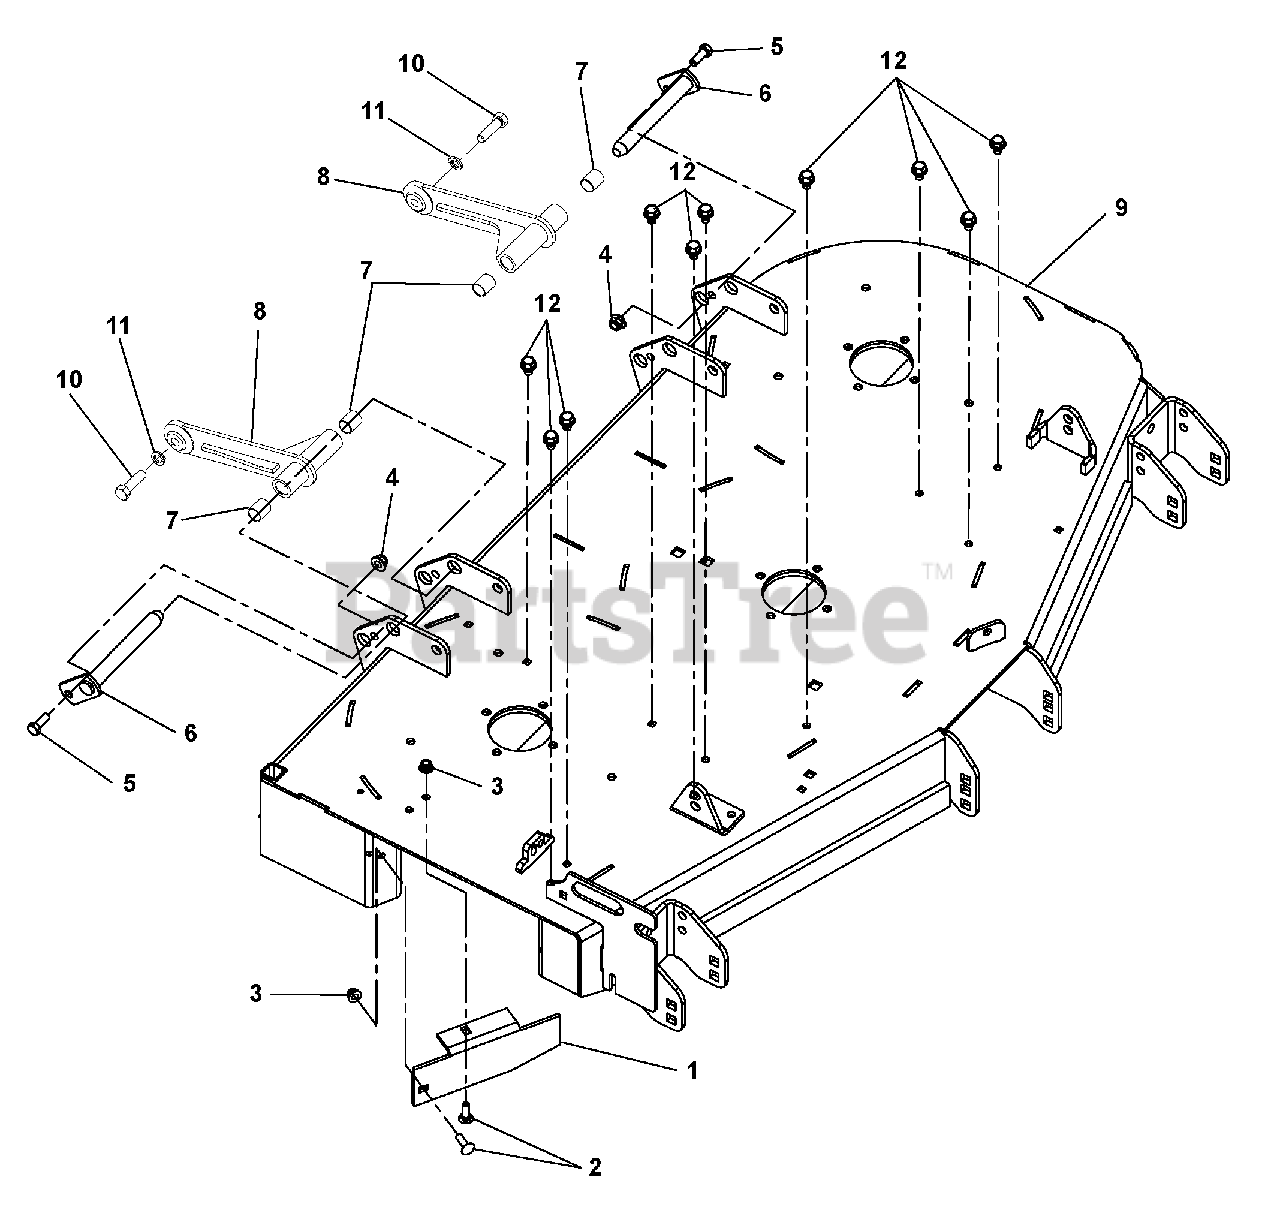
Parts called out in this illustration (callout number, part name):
1	44" - 48" Rear Discharge Baffle (062)
2	Bolt, Round Head Square Neck .31-18 x 1.00 Grade 5
3	Nut, .31-18 Nyloc Flange
4	Nut, .38-16 Nyloc Flange
5	Bolt, Hex .38-16X1.00 Grade 5
6	Weldment, Mower Mounting Pin
7	Bearing, .75 x .875 x 1.00
8	Deck Pusher Arm Weldment
9	48" 100I Side Discharge Deck (062)
10	Bolt, Hex .50-13 x 1.75 Grade 5
11	Washer, Locking .50 x .125 Regular
12	Screw, Tapping .38-16 x .50 Hex Washer Head
